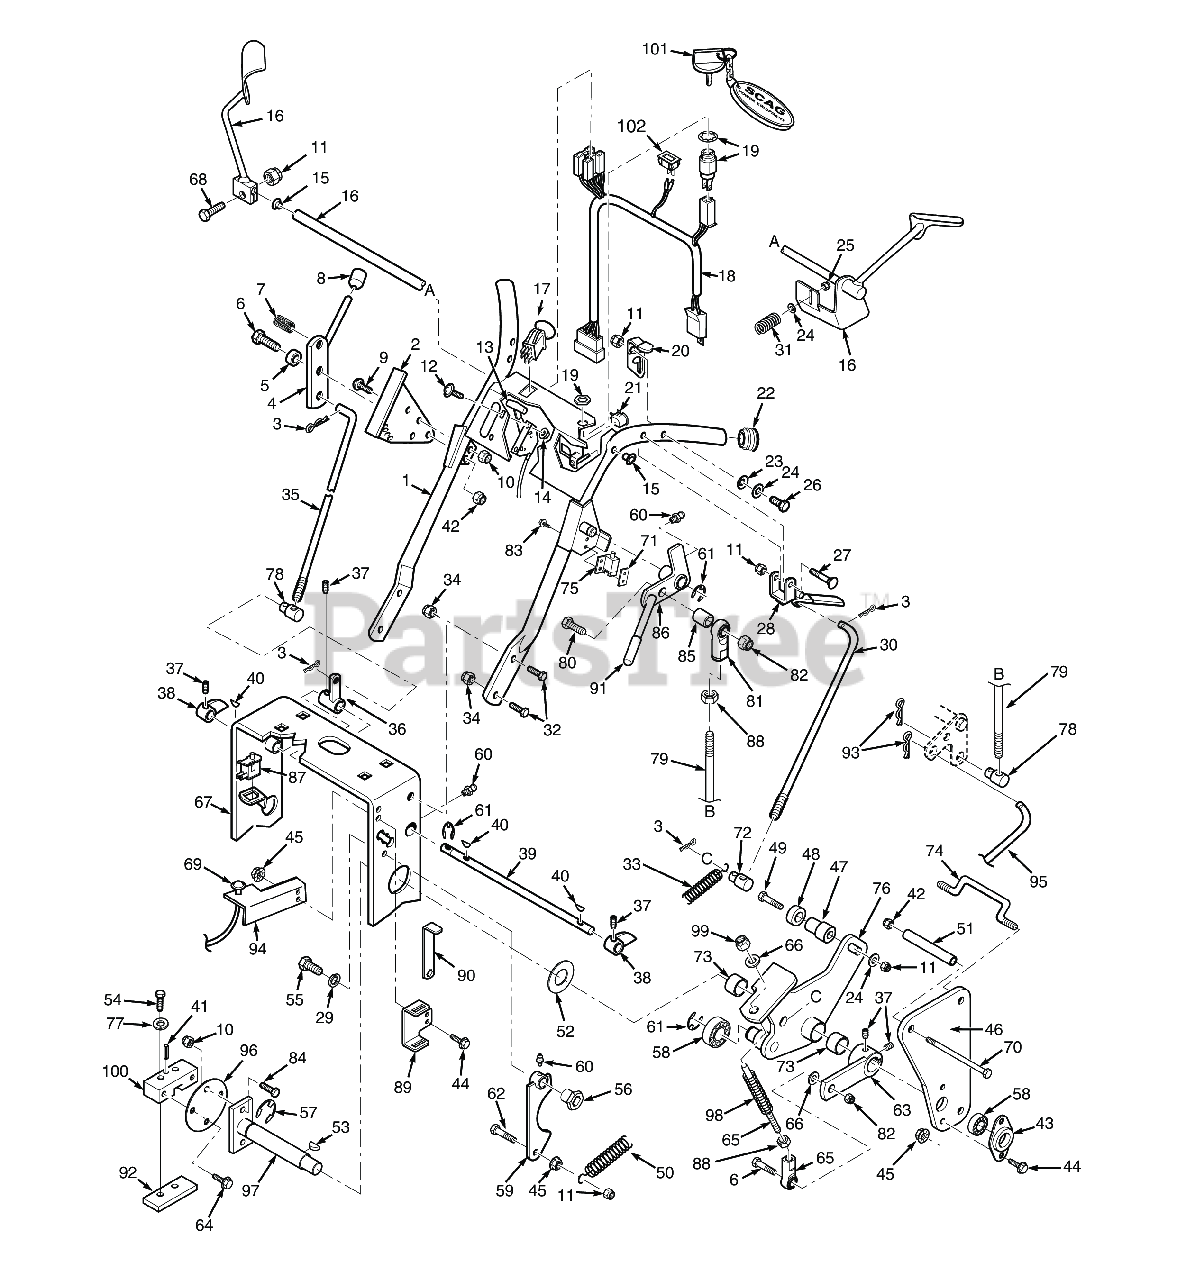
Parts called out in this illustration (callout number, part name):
1	Upper Handle Wlmt. W/Decals
2	QUADRANT, SPEED CONTROL
3	HAIR PIN, .08 DIAMETER X 1-3/16"
4	LEVER, SPEED ADJUSTMENT
5	BUSHING, SPEED ADJUSTMENT LEVER
6	Bolt, Hex Head, 3/8-16 x 1-1/2"
7	BALL PLUNGER
8	KNOB, SPEED ADJUSTMENT LEVER
9	CAPSCREW, 1/4-20 X .75 FLAT HD. HEX SOCKET
10	HEX, NUT, ELASTIC STOP LOCK, 1/4-20
11	HEX NUT, ELASTIC STOP LOCK, 5/16-18
12	SCREW, PHILLIPS WASHER HEAD #10-32 X 1/2"
13	Throttle Control (15KA & 17KA)
14	Nut, 5/16-18 Serrated Flange Hex Head
15	Bushing
16	Operator Presence Lever, RH
16	Operator Presence Lever, LH
17	Switch, PTO - 10 Amp
18	Wire Harness, Manual Start
19	KEY SWITCH, MANUAL SRT.(INCL. HWD)
20	Neutral Latch-RH 461241 Neutral Latch-LH
20	Neutral Latch Assembly, LH
21	SWITCH, NEUTRAL INTERLOCK
22	Plug, Handle Bar
23	Socket Head Capscrew #8-32 x 1/2"
24	Flatwasher, 5/16-.375 x .875 x .083 (35BV & 37BV-EFI)
25	HEX NUT, ELASTIC STOP LOCK, 5/16-18
26	Bolt, Hex Head 5/16-18 x 2-1/2" (x3) (35BV & 37BV-EFI)
27	Bolt, Hex Head 5/16-18 x 2-1/2" (35BV & 37BV-EFI)
28	Lever, Steering Control
29	Lockwasher, 3/8" Spring, Kawasaki FX / FS
30	Rod, Steering Control
31	Spring, Operator Presence
32	Capscrew, 3/8-16 x 1.0" Serrated Flange Hex Hd
33	Spring
34	NUT, 3/8-16 SERRATED FLANGE HEX HEAD
35	Rod Speed Control
36	SPEED CONTROL ARM
37	SETSCREW, 1/4-28 X 1/4 H. SOCK., KNURLED CUP
38	CAM, SPEED CONTROL(INCLUDES SETSCREW)
39	JACKSHAFT, SPEED CONTROL(FOR 16" DECK)
40	KEY, 1/8 X 1/2, WOODRUFF # 3
41	Roll Pin, Spring 3/16 x 3/4"
42	HEX NUT, ELASTIC STOP LOCK, 5/16-18
43	FLANGE, JACKSHAFT BEARING
44	Cpscrw, 5/16-18 x 1"Serrated Flange Hex Head
45	Nut, Serrated Flange 5/16-18 (Right Front Engine Mounting, Briggs and Kohler Only)
46	Plate, Side
47	Support, Neutral Support
48	BEARING, SPEED CONTROL BELLCRANK
49	BOLT, HEX HD., 5/16-18 X 1-3/4 FULL THREAD
50	SPRING, IDLER TENSION
51	Spacer, Side Plate
52	Flatwasher, 3/4 (.766 x 1.250 x .060)
53	KEY, WOODRUFF #9, 3/16 X 3/4"
54	SERR. FLG. HEX HEAD CAPSCREW, 5/16-18 X 3/4
55	Bolt, Hex Head, 3/8-16 x 1 Gr. 5
56	B ushing, Brake
57	RETAINING RING, 3/4" EXTERNAL "E"
58	BEARINGS, BALL, NEUTRAL RETURN
59	Cam, Neutral (incl. grease ftng.)
60	Greese Fitting, Straight 1/4 - 28
61	RETAINING RING, 5/8" EXTERNAL "E"
62	Bolt, Heax Head 5/16-18 x 1" (48V / 52V)
63	Lever, Speed Control
64	Bolt, Serrated Flange Hex Head 1/4 x 20 x 3/4"
65	Linkage Assembly
66	Flatwasher, 3/8" Special (.391 x .938 x .105)
67	Engine Deck (16" Wide) with Decals - Small Frame
68	Bolt, 5/16 - 18 x 1 - 1/4" Hex Head
69	Choke Control
70	Bolt, Hex Head 3/8-16 x 4-1/4"
71	Plate, Threaded
72	Swivel Joint, Steering Rod
73	Bushing, oil lube - 3/4 ID x 1.0
74	Rod, Offset
75	Switch, Interlock (see below)
76	Control, LH (inc. bush. & decal)
76	Control, RH (inc. bush. & decal)
77	Lockwasher, 1/4� Spring
78	SWIVEL JOINT, SPEED CONTROL ROD
79	Rod, Brake Lever
80	Capscrew, Hex Head 3/8-16 x 2.0"
81	Rod End, 3/8-24 RH Thread Female
82	HEX NUT, ELASTIC STOP LOCK, 3/8-16
83	Screw, Hex-Slotted Washer Head #10 32 x 3/4"
84	BOLT, HEX HEAD, 1/4-20 X 3/4 GR.5
85	Spacer, Idler
86	Parking Brake Lever w/Grip & Grease Fitting
87	SWITCH, NEUTRAL INTERLOCK
88	HEX NUT, 3/8-24 R.H. THREAD
89	Mounting Bracket, Wrench
90	Wrench
91	GRIP, PARKING BRAKE
92	CLAMP PLATE, PUMP CONTROL
93	COTTER PIN, HAIR - 0.94 X 1.62
94	Bracket, Choke Mounting
95	Rod, Brake Lower
96	Plate, Coupler
97	Shaft, Pump Control
98	Spring, Tracking Adjustment
99	HEX NUT, ELASTIC STOP LOCK, 3/8-16
100	BLOCK, PUMP CONTROL
101	Key, Assembly w/Fob
101	Key w/Shroud Only
102	Hour Meter, Inductive
